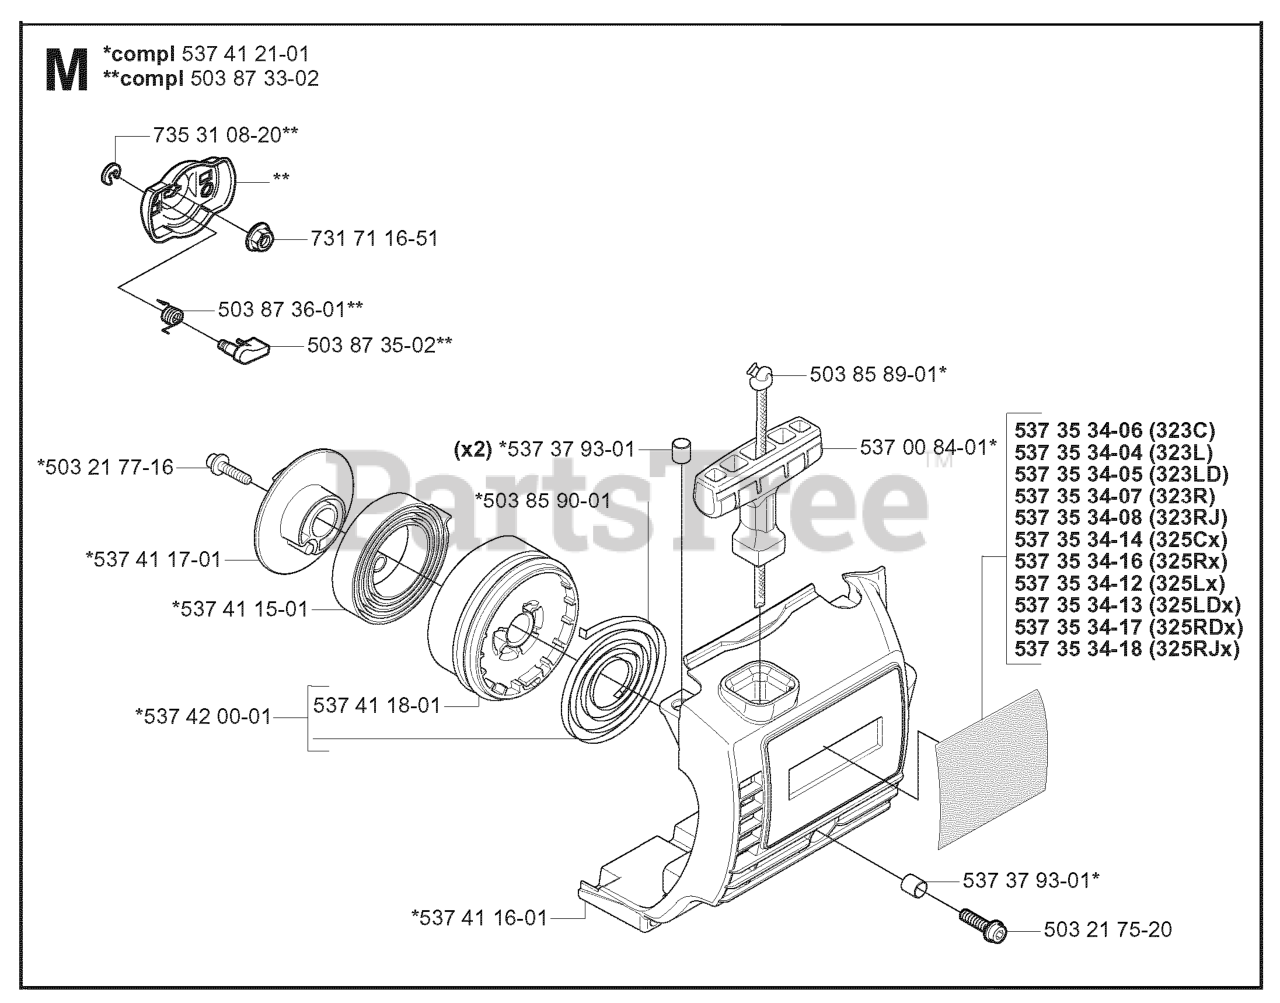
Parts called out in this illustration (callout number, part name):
1	DECK W/DECALS 61" HUS WSL
2	RP PULLEY - 61"
4	HCS 5/16C X 1
5	NUT 5/16C CENTERLOCK
6	SPINDLE WASHER
7	WASHER 7/16 LOCK
8	HCS 7/16F X 1 1/2
9	BLADE OEM 21" (61" DECK)
10	LOCKWASHER 5/8
11	HCS 5/8F X 1 1/4
12	MAIN BAFFLE - 61" BLK
13	CENTER BAFFLE - 61
14	CARRIAGE BOLT 5/16C X 5/8"
15	WASHER 5/16 FLAT
16	ANTI-SCALP ROLLER
18	HCS 3/8C X 3 1/2
19	WASHER 3/8 FLAT
20	NUT 3/8C CENTERBLOCK
21	BELT SHIELD 61" RIGHT
22	SUPPORT PLATE
23	BELT, DECK
24	IDLER BUSHING
25	IDLER PULLEY
26	IDLER PULLEY (TALL)
27	HCS 3/8C X 2 1/2
28	WASHER, SUPPORT
29	KNOB, THREE PRONG
30	STRUT WELDMT, L.H.
31	ZERK
32	SPACER, STRUT
33	PIN WELDMENT
34	HCS 5/16C X 3/4
35	CHUTE 61 ORANGE
36	DECK SPRING
37	4CS 3/8C X 1 SERRATED HEAD
38	NUT 1/2-13 HEX NYLOC ZD
39	WASHER 1/2 FLAT
41	PIVOT BUSHING
42	HCS 1/2C X 3 1/4
43	SPINDLE ASSY - 52/61"
44	SHAFT SEAL
46	52/61 SPINDLE - SPLINED SHAFT
47	BOTTOM DUST CAP
48	TOP DUST CAP
49	PLUG-VENTED
50	JACKSHAFT ASSY LOWER
51	SHAFT SEAL
53	JACKSHAFT SPINDLE
54	BOTTOM DUST CAP
55	TOP DUST CAP
56	PLUG-VENTED
57	HCS 7/16C X 1 1/2
58	KEY 1/4 SQ X 1 1/8
59	SPINDLE WASHER
60	SHEAVE WSL
61	WASHER 7/16 LOCK
62	ZERK
539108610	BELT SHIELD 61" LEFT
